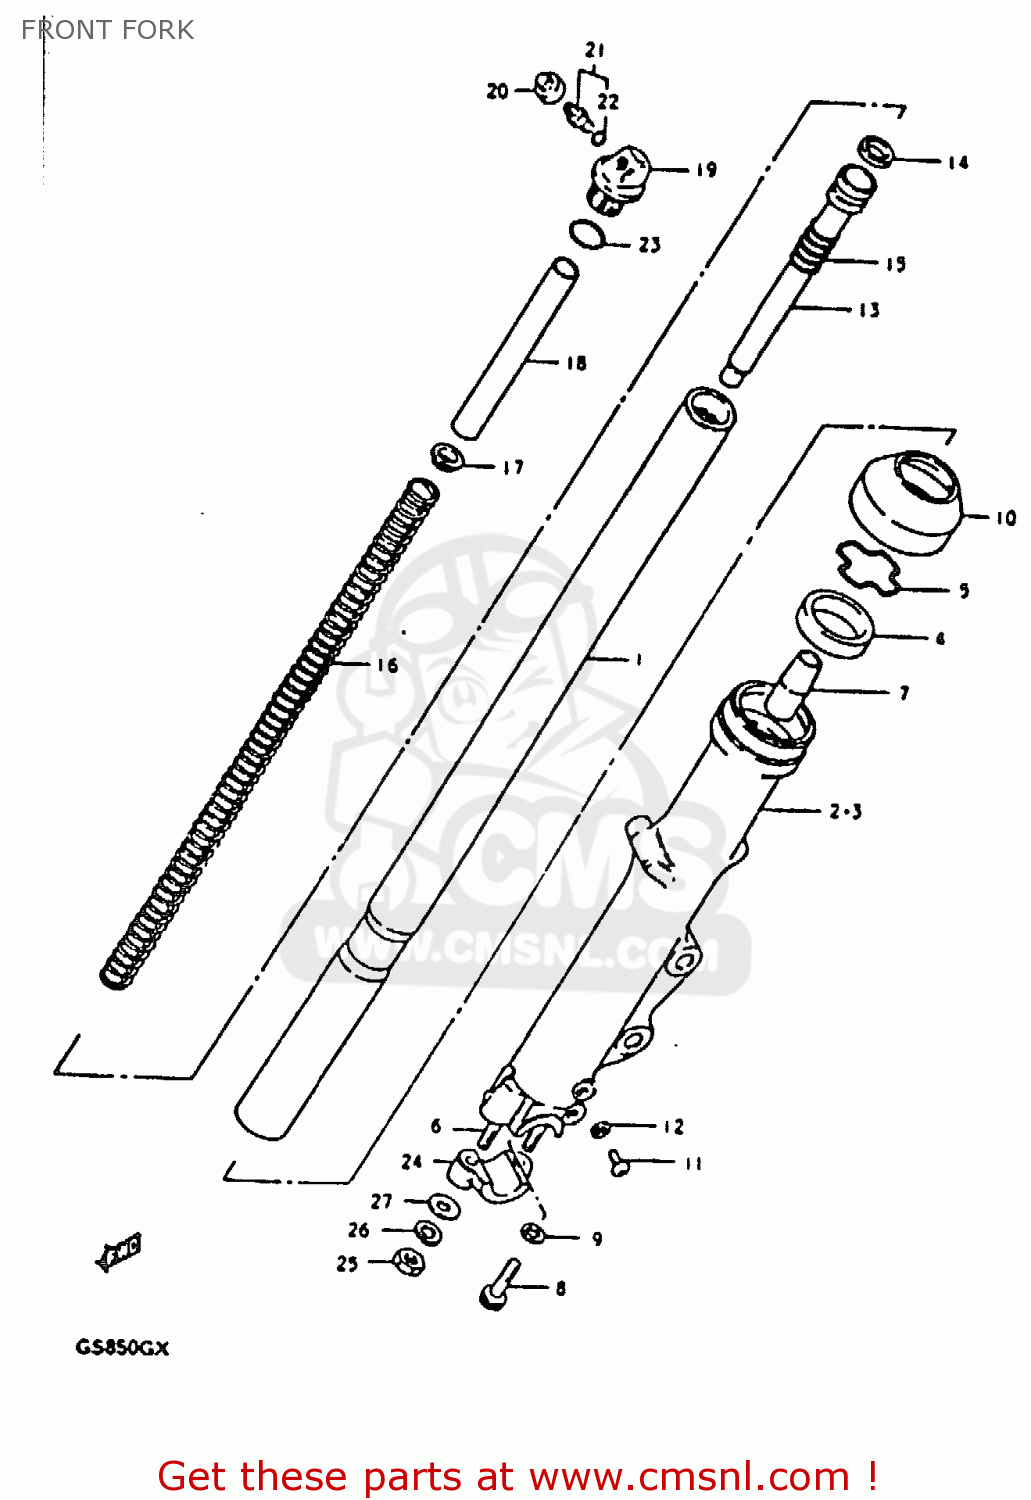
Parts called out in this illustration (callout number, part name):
1	TUBE,FORK,INNER
2	TUBE,FORK,OUTER,RIGHT
3	TUBE,FORK,LEFT,OUTER
4	OIL SEAL,FRONT FORK
5	RING,STOPPER
6	STUD BOLT
7	PIECE,OIL LOCK
8	BOLT,FORK CYLINDER(10X25)
9	GASKET (NAS)
10	SEAL,DUST
11	SCREW
12	GASKET,DRAIN,PLUG (NAS)
13	CYLINDER,FRONT FORK
14	RING,PISTON
15	SPRING,REBOUND
16	SPRING,FRONT FORK
17	GUIDE,FRONT FORK SPRING C
18	SPACER,SPRING
19	CAP
20	CAP,VALVE
21	VALVE
22	O RING
23	O RING
24	HOLDER,AXLE
25	NUT (8MM)
26	LOCK WASHER
27	WASHER
